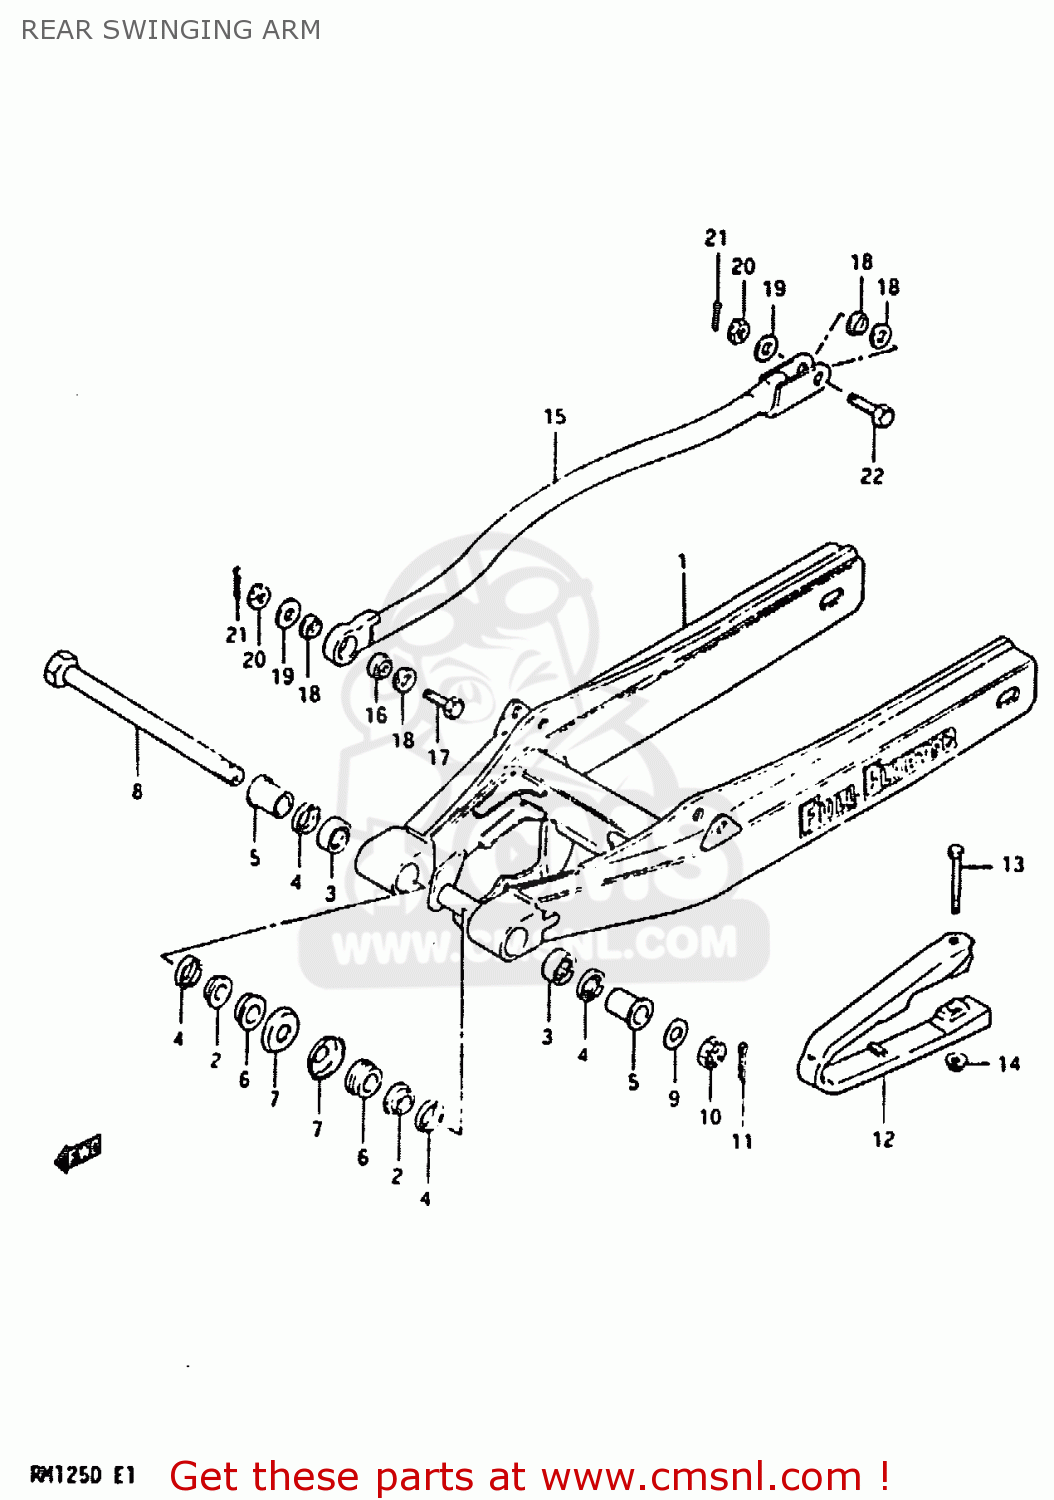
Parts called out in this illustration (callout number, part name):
1	SWING ARM ASSEMBLY,REAR
2	BUSH,RR SWINGINGARM PIVOT
3	BEARING(20X27X20)
4	OIL SEAL
5	SPACER,RR SWGARM PIVOT
6	SPACER,RR SWGARM PIVOT INNER
7	COVER,RR SWGARM DUST SEAL
8	SHAFT,RR SWINGINGARM PIVOT
9	WASHER
10	NUT 14MM
11	COTTER PIN
12	BUFFER,CHAIN TOUCH DEFENSE
13	BOLT(6X70)
14	NUT
15	TORQUE LINK SET,RR
16	SPHERICAL BEARING,TORQUE
17	BOLT 8X28
18	19
19	WASHER
20	NUT 8MM
21	PIN 20X20
22	BOLT 8X29.5
